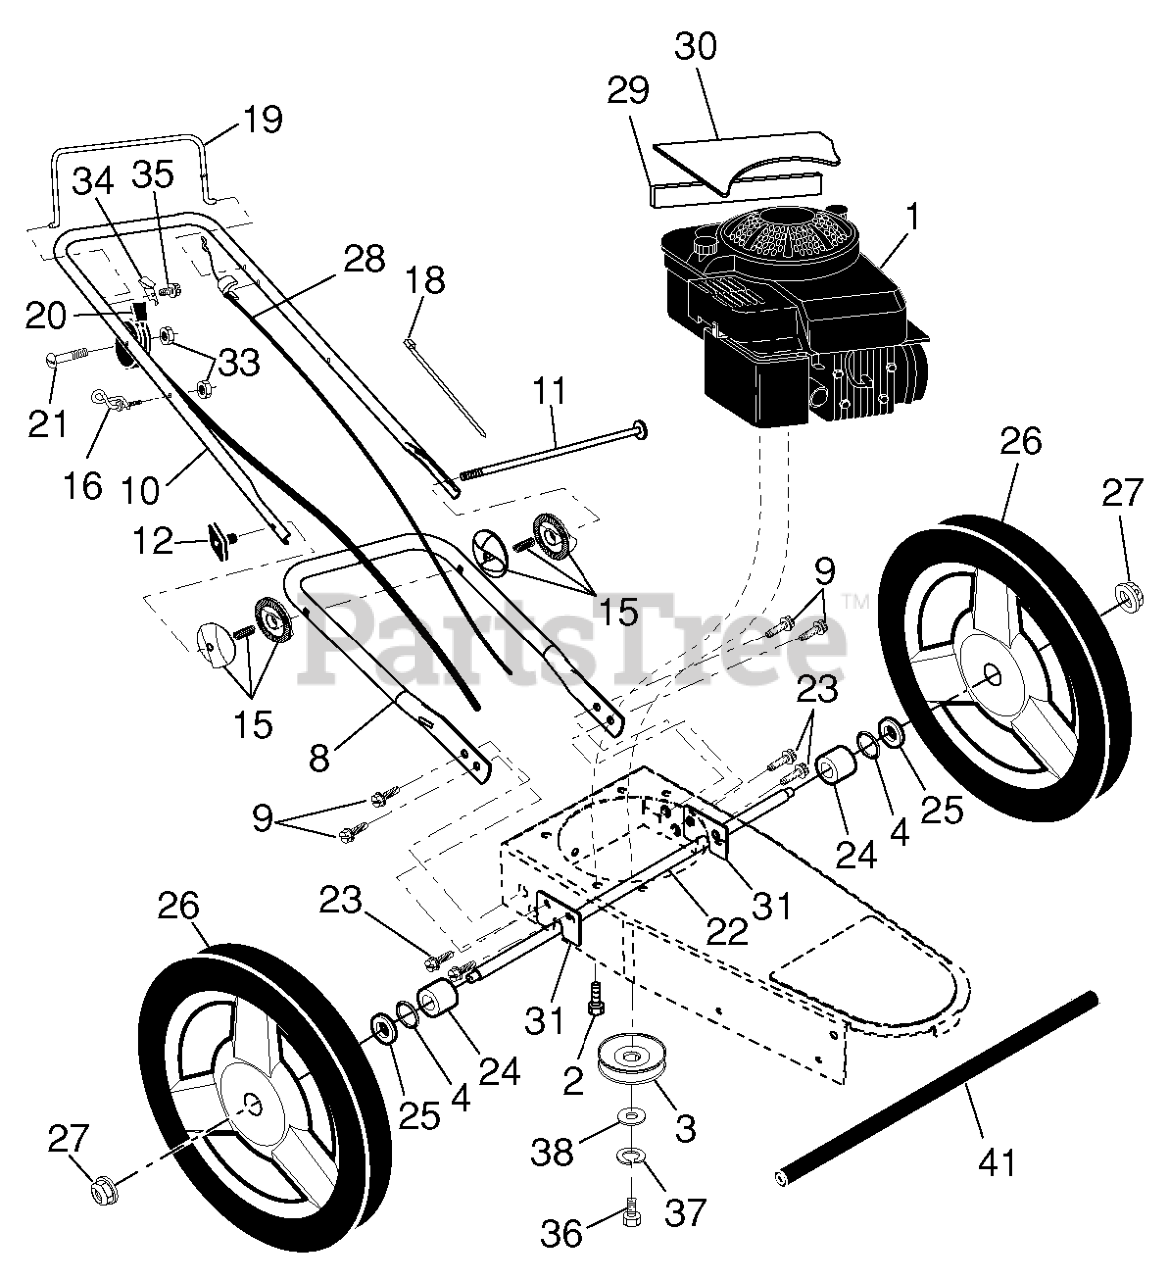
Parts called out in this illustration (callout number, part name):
2	BOLT 3/8-16X1-1/8
3	PULLEY, ENGINE
4	O-RING..070X.487.NEOPRENE
8	HANDLE.LOWER.STRING.TRIMMER.GR
9	BOLT.HEX.HD.WASHER.5/16-18X.75
10	HANDLE.UP.STRING.TRIMMER.GREY
11	BOLT.HANDLE.WHEELED.TRIMMER
12	KNOB.WING.PLASTIC.BLACK
15	ADJSTR.ASSEM.HANDLE.WHLD.TRIMM
16	RB GUIDE.ROPE.STD.BLK.ZIN WSL
18	TIE GUIDE
19	BAIL.SPINDLE.ENGAGE.BLACK
20	RP CONTROL.THRO.S-TRM.SNPIN.BS
21	SCREW.PAN.HEAD
22	AXLE SHAFT ASSEMBLY
23	BOLT.HEX.HD.WASHER.5/16-18X.75
24	SPACER.AXLE.STRING.TRIMMER
25	WASHER.FLAT.1/2
26	WHEEL.12X1.75.CF.H3SPKRAD3
27	NUT.HEX.FLANGE.3/8-16.LOCKNUT
28	CONTROL.DRIVE.TRIMMER.WHEELED
29	DECAL, WARNING
30	DECAL, WARNING
31	BRACKET, AXLE
33	NUT
34	BRACKET.UPSTOP.RT
36	SCREW, HEX HD 3/8-24 X 1-3/8
37	LOCKWASHER
38	WASHER,HARDEN
41	TUBE.AXLE.TRIMMER.BLACK
